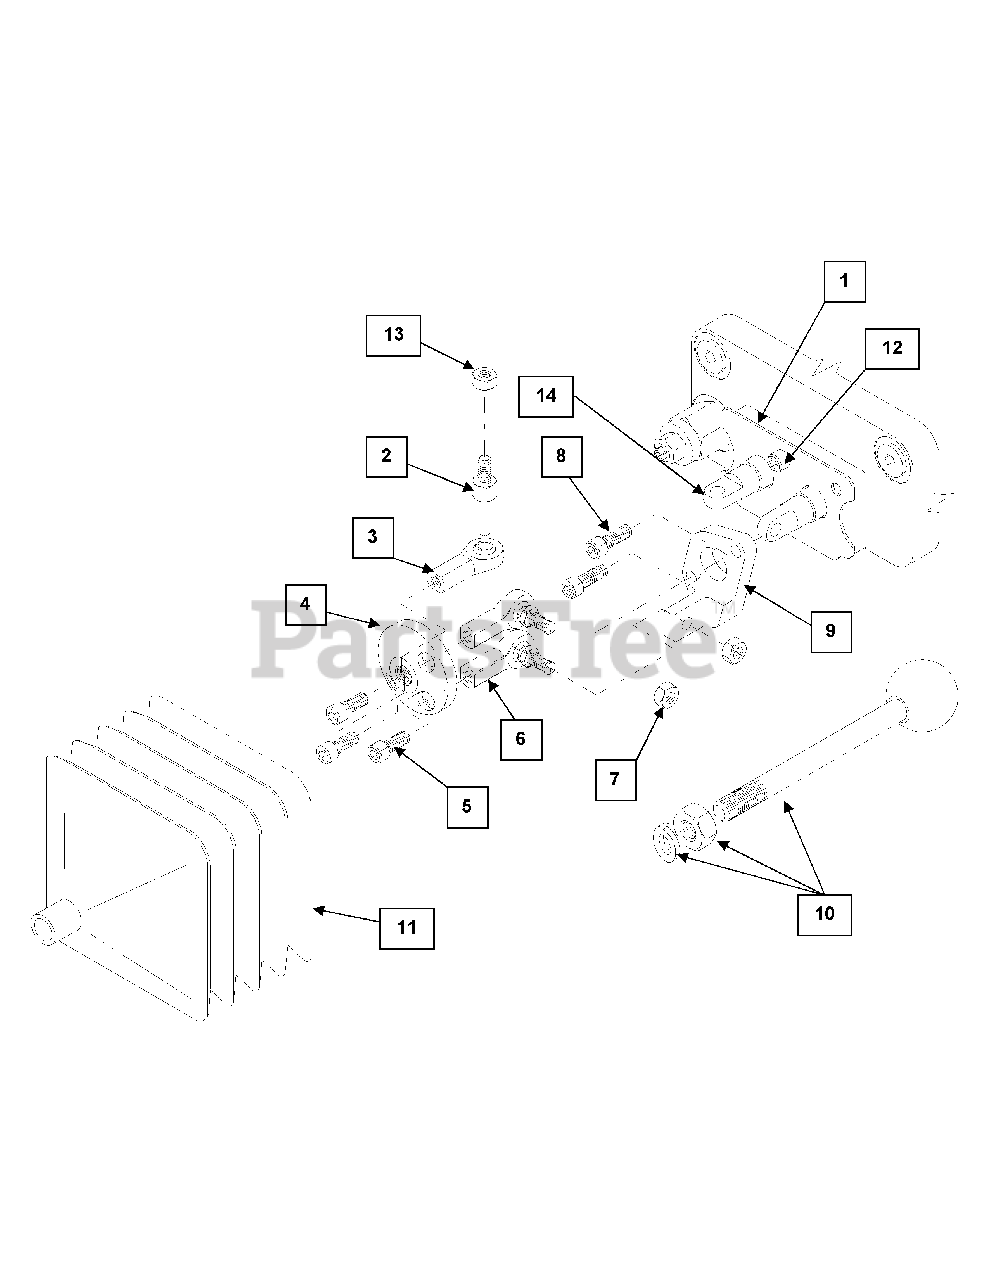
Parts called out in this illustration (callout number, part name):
1	Mounting Plate
4	Adapter Plate
6	Rod End Assembly
7	Hex Nut (Coarse Thread)
13	Hex Nut (Fine Thread)
14	Spool End Adapter
